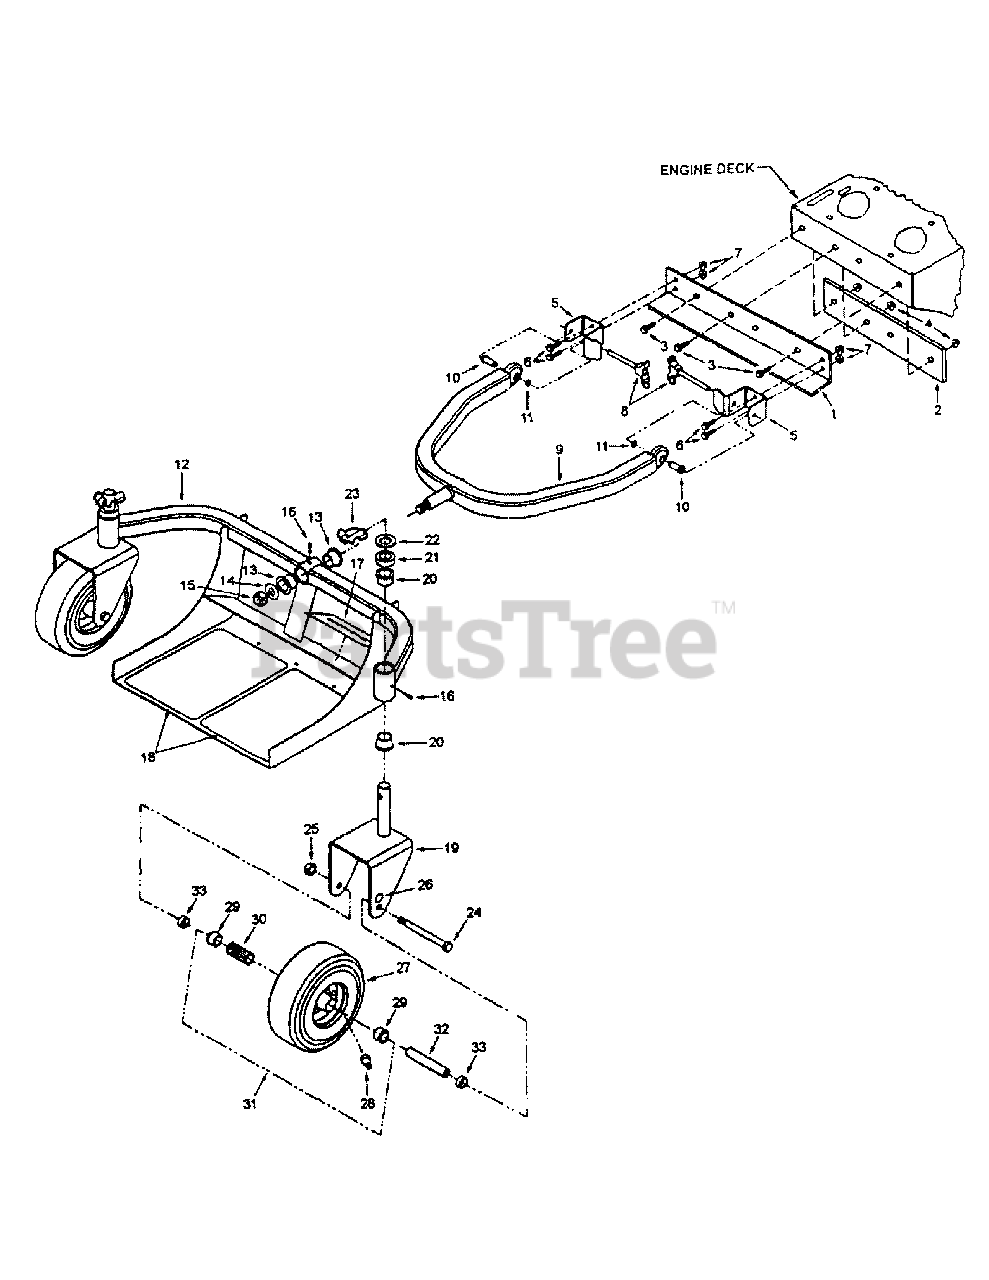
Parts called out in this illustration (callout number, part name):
1	Adapter Bar
2	Support Bar
3	Cap Screw, 3/8-16 x 1 Hex Hd.
4	Hex Nut, 3/8-16 Stover
5	Mounting Bracket
7	Hex Nut, 3/8-16 Flanged Lock
8	Pin, Quick Release, 3/8
9	Tubing, A-Frame
10	Spacer, Shoulder, .378 I.D. x.50 O.D.
11	Retainer Ring
12	Footstand, Sulky
13	Flange Bearing, Metal
14	Flat Washer, .750 x 1.50 x .120 Thk.
15	Hex Nut, 3/4-16 Center Lock
16	Grease Fitting
17	Safety Decal
18	Foot Pad, Abrasive
19	Caster Fork
20	Flange Bearing, Plastic
21	Spacer, 1.015 I.D. x 1.62 O.D. x.50 Lg.
22	Washer
23	Pin, Klik
24	Cap Screw, 1/2-20 x 5.5 Hex Hd.
25	Hex Nut, 1/2-20 Center Lock
26	Decal, Inflation Info
27	Tire, 9.00 x 3.50 x 4 Smooth
28	Air Valve, Tubeless
29	Flange Bearing, Graf Oil
30	Roller Bearing
31	Wheel Assembly, Caster
32	Spacer, Wheel
33	Spacer, .812 ID x .268 LG
